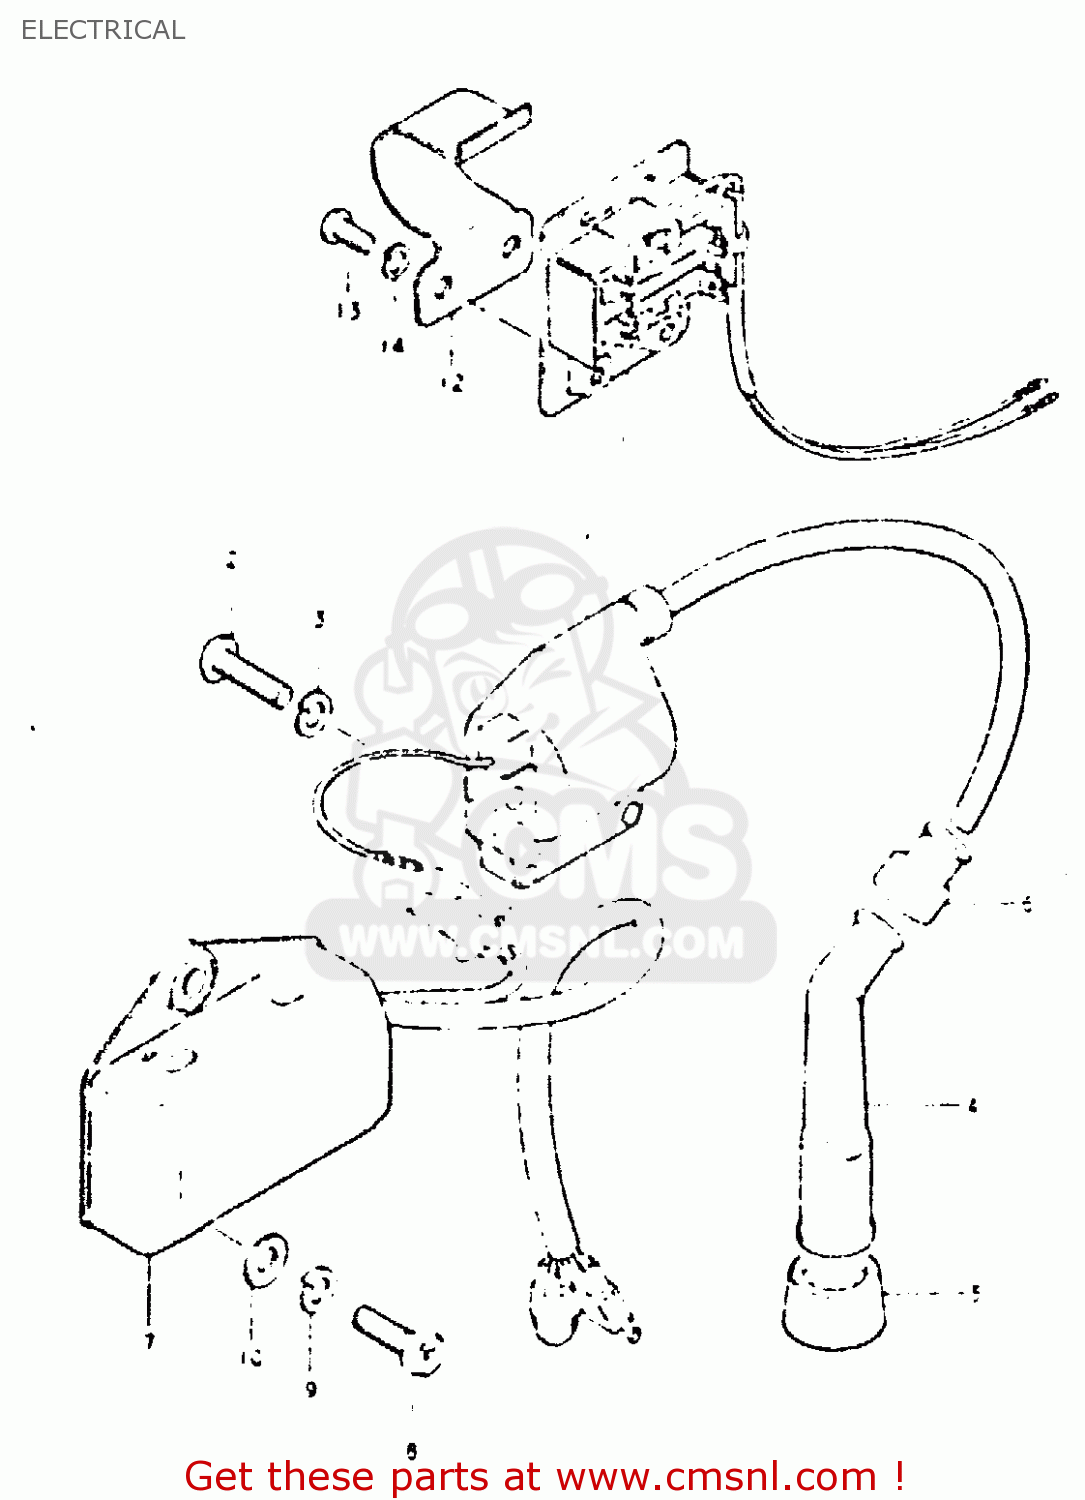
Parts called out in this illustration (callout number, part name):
1	COIL ASSEMBLY,IGNITION
2	SCREW
3	LOCK WASHER
4	CAP ASSY,SPARK PLUG
5	SEAL,SPARK PLUG
6	SEAL,SPARK PLU
7	CDI UNIT
8	SCREW
9	LOCK WASHER
10	WASHER
